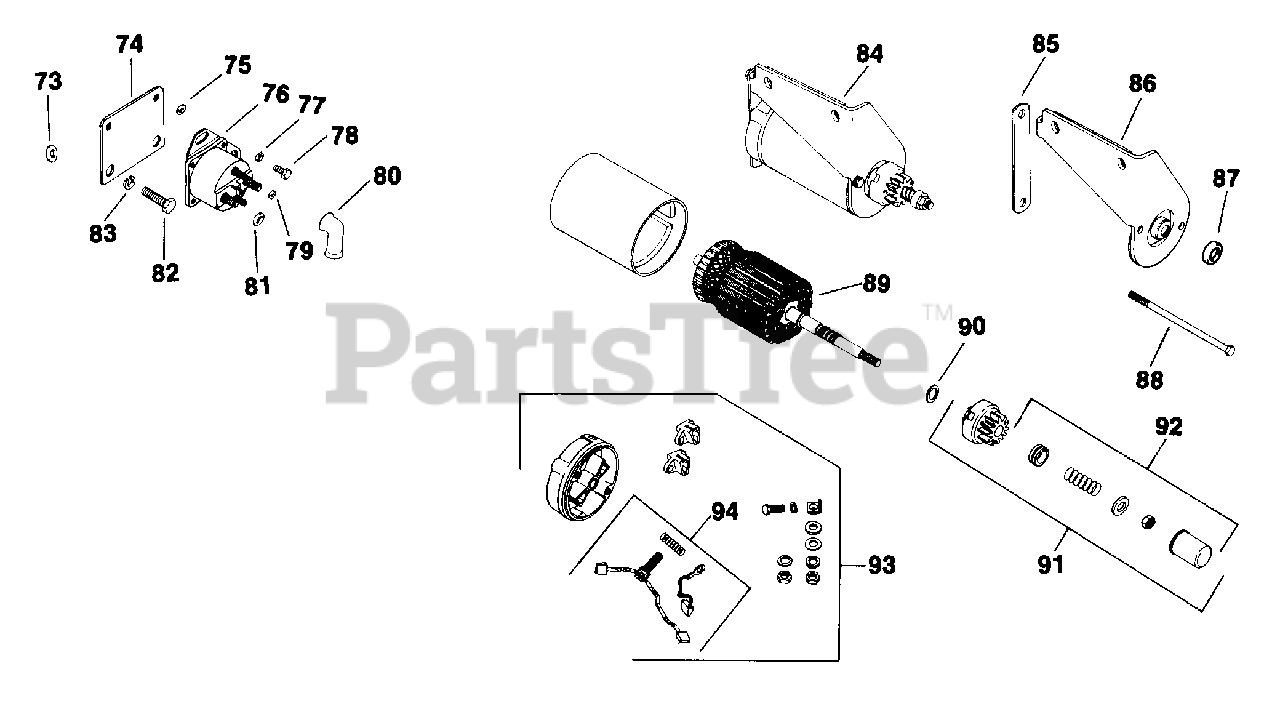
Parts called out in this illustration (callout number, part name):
73	WASHER, FLAT 13/32"
74	BRACKET - DISCONTINUED
75	WASHER, FLAT 1/4" (O.D. 1/2")
76	Switch, relay
77	WASHER, SPRING LOCK 1/4"
78	SCREW, CAP HD 1/4-20X1/2"
79	WASHER, INT TOOTH LOCK #10
81	WASHER, INT TOOTH LOCK 5/16"
82	SCREW, CAP HD 3/8-16x1"
83	WASHER, SPRING LOCK 3/8"
84	STARTER - USE 41 098 07
